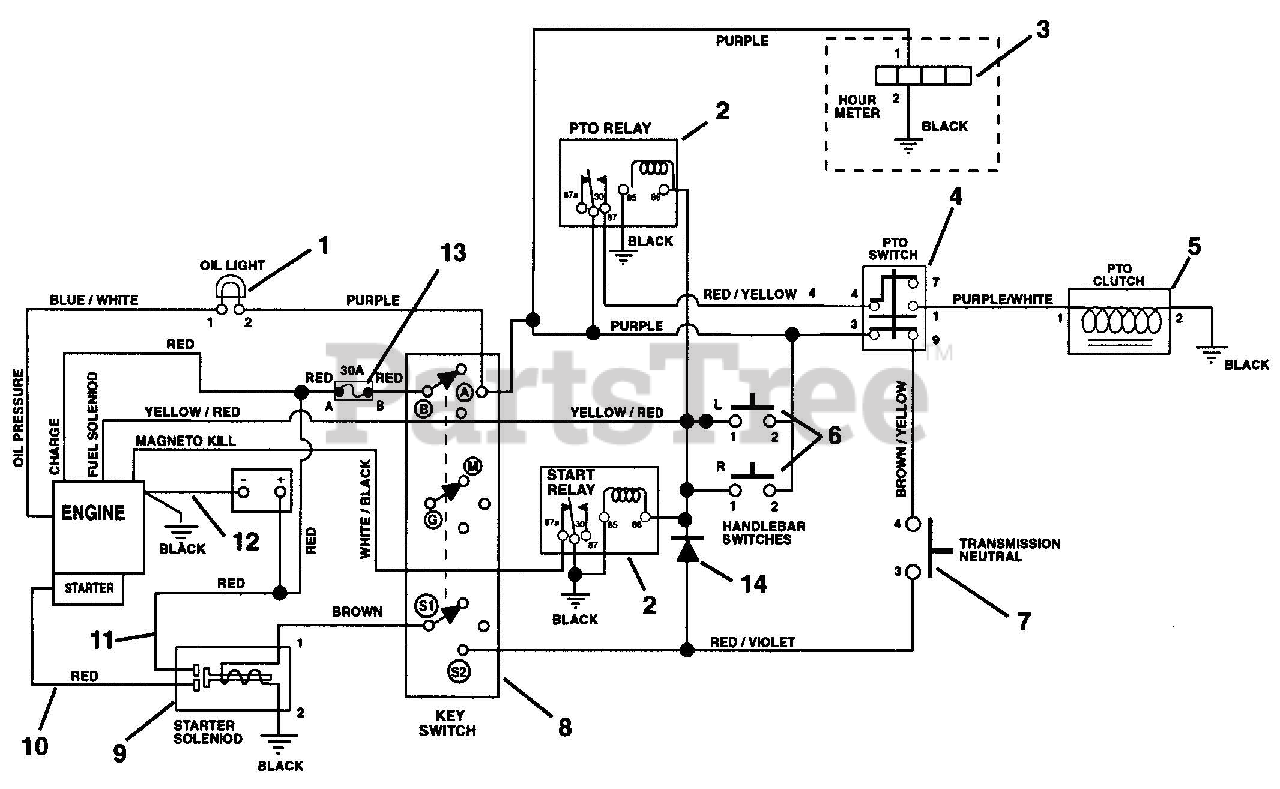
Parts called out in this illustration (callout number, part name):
1	Light - Indicator
2	Relay
3	Hour Meter
4	Switch - Clutch with Retainer
5	Clutch - Electric
7	Switch - Interlock
8	Key Switch
9	Solenoid
10	Cable - Starter
11	Cable - Battery to Solenoid
12	Cable - Negative Battery
13	Fuse - 30 AMP
